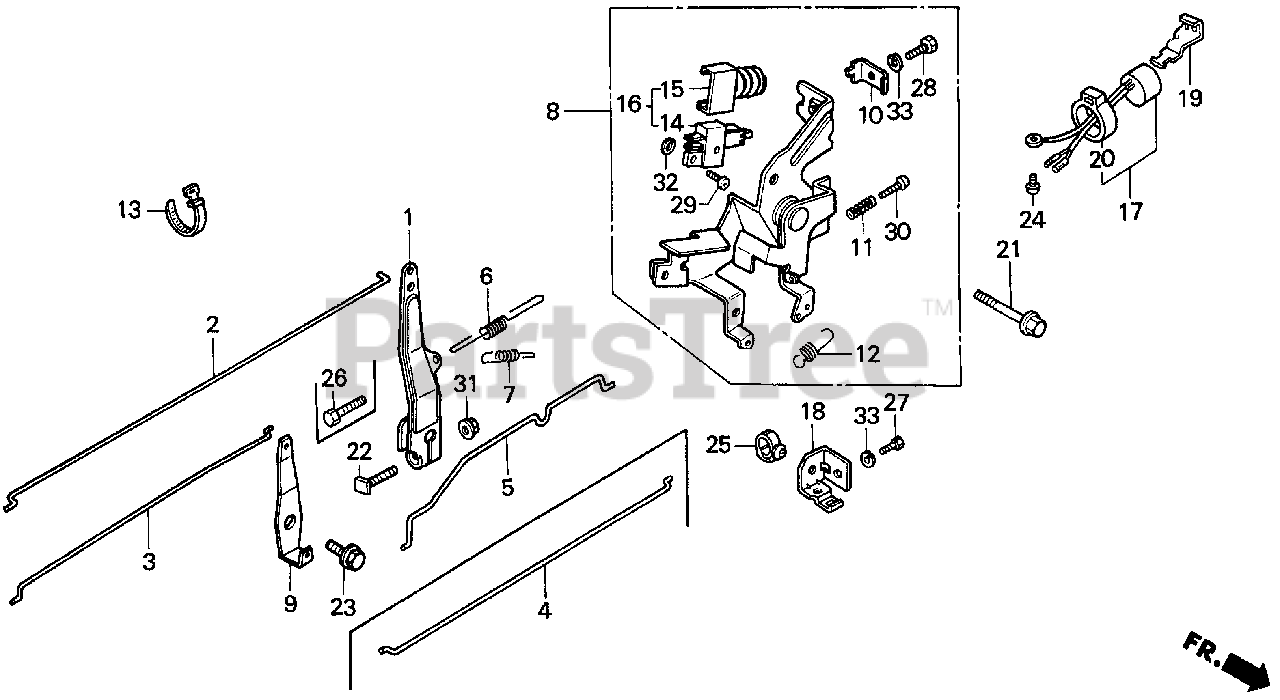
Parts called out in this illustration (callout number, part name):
1	ARM, GOVERNOR
2	ROD, GOVERNOR
3	ROD, CHOKE
4	ROD, JOINT
5	ROD, JOINT
6	SPRING, GOVERNOR
7	SPRING, GOVERNOR PRIMARY
8	CONTROL ASSY.
9	LEVER, CHOKE JOINT (NOT AVAILABLE)
10	HOLDER, CABLE
11	SPRING, CONTROL ADJUSTING
12	SPRING, CABLE RETURN
14	SWITCH ASSY., ENGINE
15	COVER, SWITCH
16	SWITCH ASSY., ENGINE STOP
21	BOLT, FLANGE (6X12) (CT200)
22	BOLT, GOVERNOR ARM
23	BOLT, FLANGE (6MM)
26	BOLT, HEX. (6X22)
28	BOLT, SLOT (5X16)
29	SCREW, PAN (4X14)
30	SCREW, PAN (5X20)
31	NUT, FLANGE (6MM)
32	WASHER, SPRING (4MM)
33	WASHER, SPRING (5MM)
